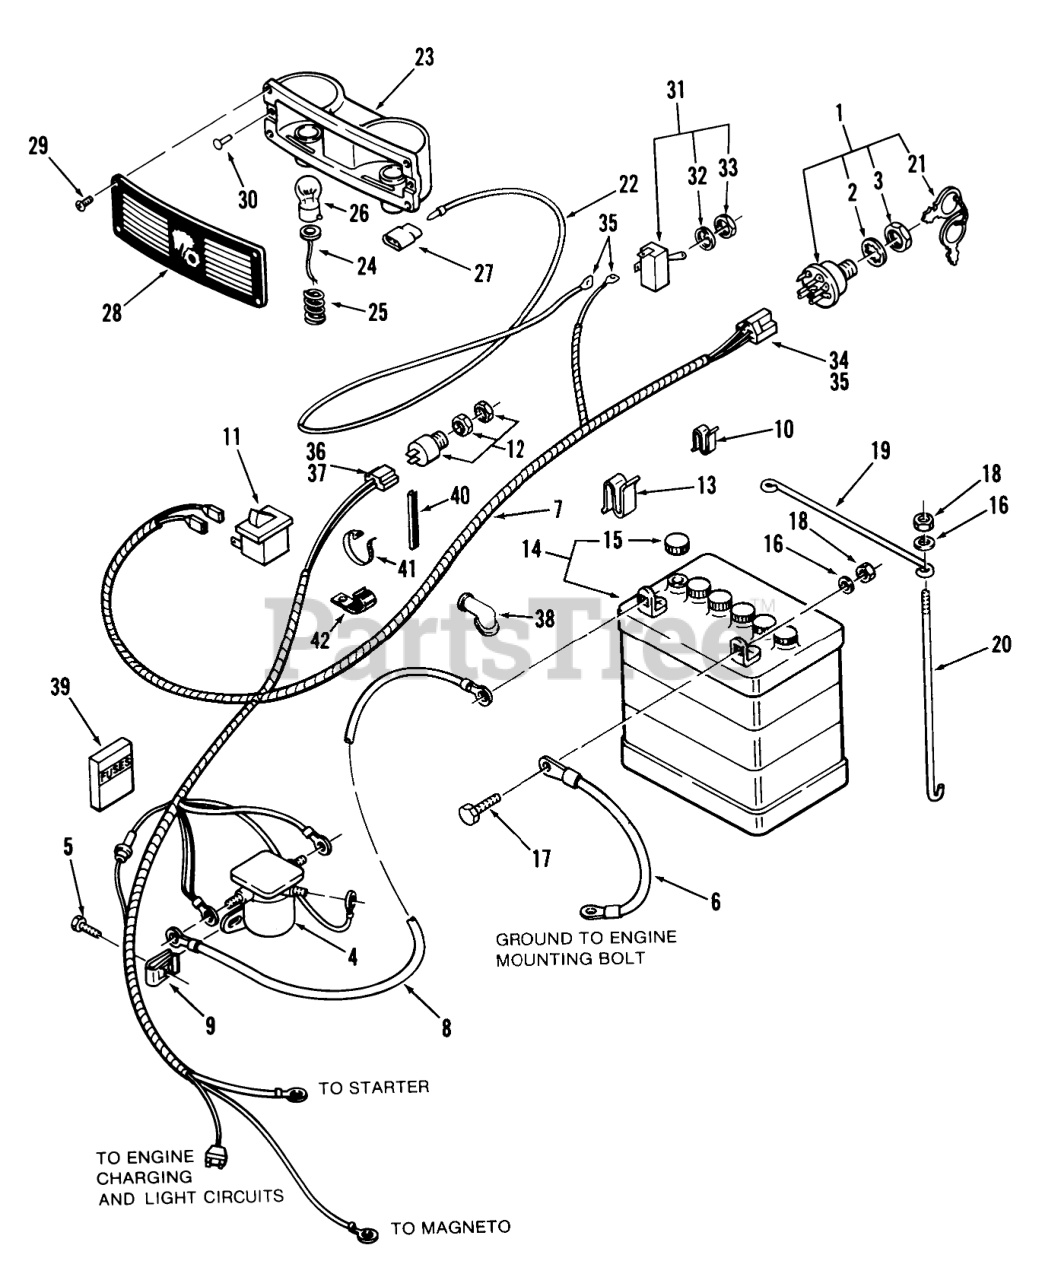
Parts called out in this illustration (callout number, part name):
1	ASSY-SWITCH IGNITION
2	LOCKWASHER
4	Solenoid
5	HEX WASHER HD SCREW
6	Wire
7	WIRING HARNESS ASSY
8	Cable-Solenoid To Batt. Pos
9	Speed Nut
10	SPEED CLIP
11	SWITCH INTERLOCK
12	SWITCH
13	Clip
14	Battery
17	Bolt
18	Nut
19	ROD-HOLD DOWN
20	Hook
21	Key-EL
22	WIRE-LIGHT
23	ASSY REFLECTOR HOUSI
24	WIRE ASSY
25	SPRING
26	BULB
27	CONNECTOR 3 WIRE
28	Lens
29	Pan HD Swage
30	RIVET
31	SWITCH-LIGHTS
32	TAB-WASHER
33	NUT-HEX
34	CONNECTOR-5 WAY-SERV
35	Terminal
36	Connector Body
37	Female Terminal
38	Terminal Cover
40	EDGE TRIM 4IN OF 102896
41	Cable Tie
42	CLIP
